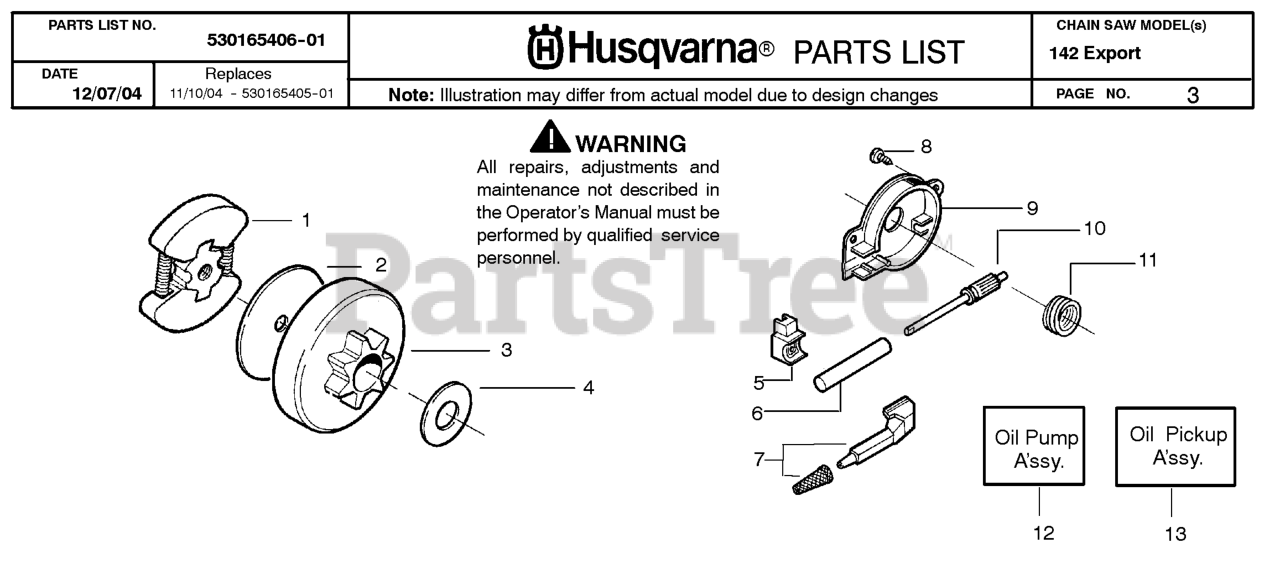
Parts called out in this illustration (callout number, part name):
1	CLUTCH ASSEMBLY
2	FRICTION DISC,CLUTCH 36/41
4	THRUST WASHER
5	PRESSURE SEAL,OILER 36/41
6	OIL PUMP BARREL
7	OIL PICKUP
9	OIL PUMP HOUSING
10	PLUNGER & GEAR ASSEMBLY
11	OILER GEAR 36/41
12	OILER ASS'Y 36/41
13	SERVICE KIT-OIL PICKUP 36/41
530047061	CLUTCH DRUM ASSY
530048132	ASSY CLUTCH DRUM .325"
